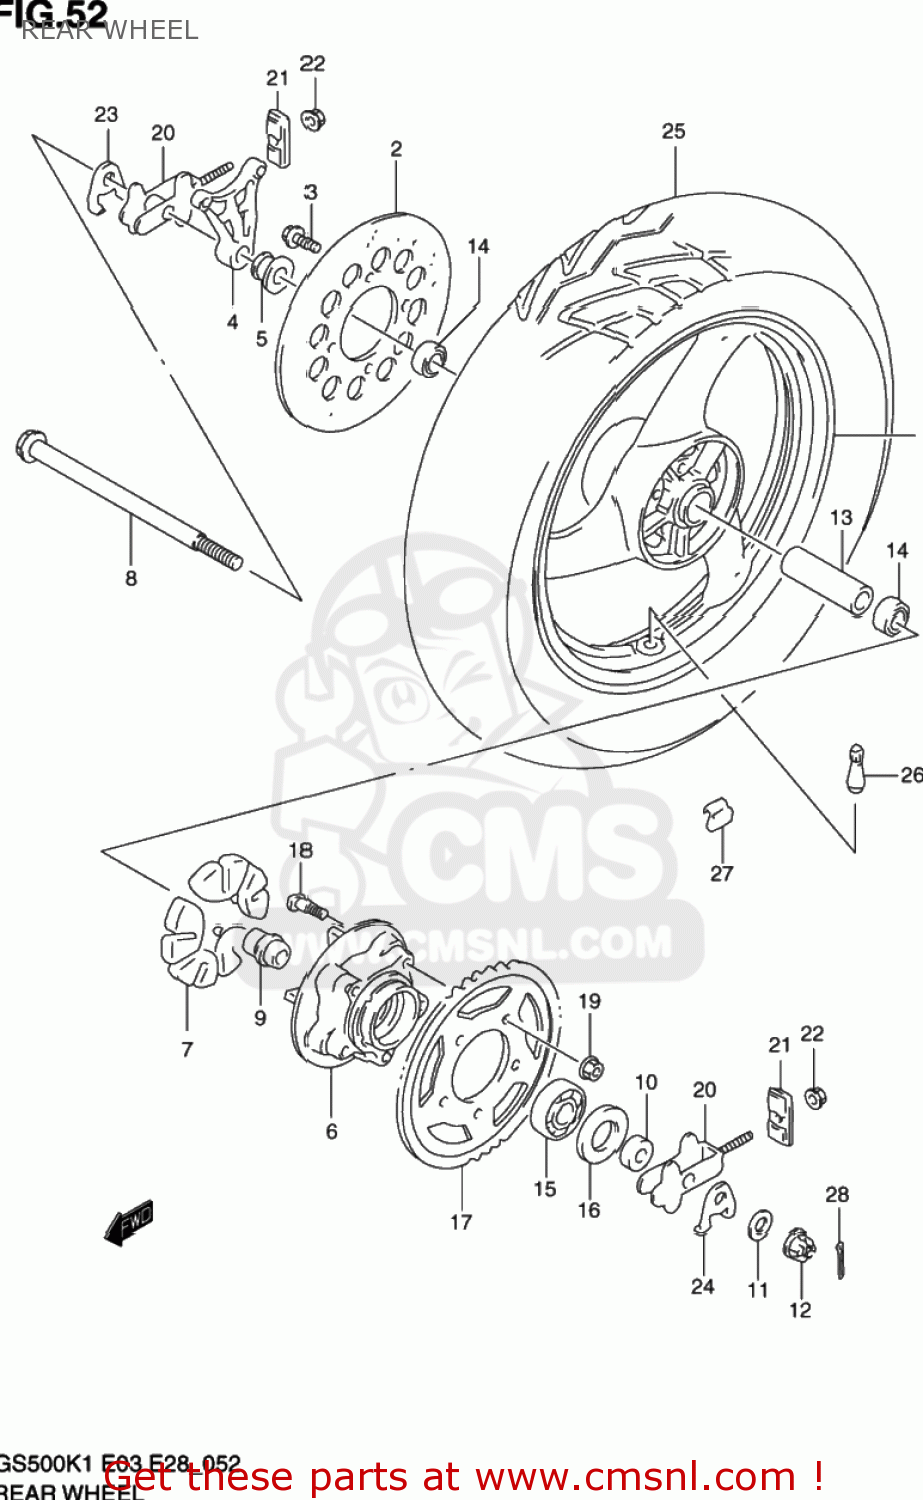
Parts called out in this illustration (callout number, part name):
1	WHEEL,REAR,MT3
2	DISC,RR BRAKE
3	BOLT(8X30)
4	BRACKET,RR,CALIPER
5	SPACER,RR AXLE,R
6	DRUM,RR SPROCKET
7	ABSORBER,RR HUB SHOCK
8	AXLE,RR
9	RETAINER,RR SPROCKET DRUM
10	SPACER,RR AXLE,L
11	WASHER(17X30X3)
12	NUT
13	SPACER(17.5X25X88)
14	BEARING
15	BEARING(25X62X17)
16	SEAL,OIL(35X62X8)
17	SPROCKET,RR(NT:39-520)
18	BOLT
19	NUT
20	ADJUSTER,CHAIN
21	PLATE,CHAIN ADJUSTER GUIDE
22	NUT
23	WASHER,CHAIN ADJUSTER
24	WASHER,CHAIN ADJUSTER
25	TIRE,T/L(130/70-17 62H)
26	VALVE ASSY,WHEEL RIM(TR412)
27	BALANCER,WHEEL (10G)
28	PIN,COTTER
